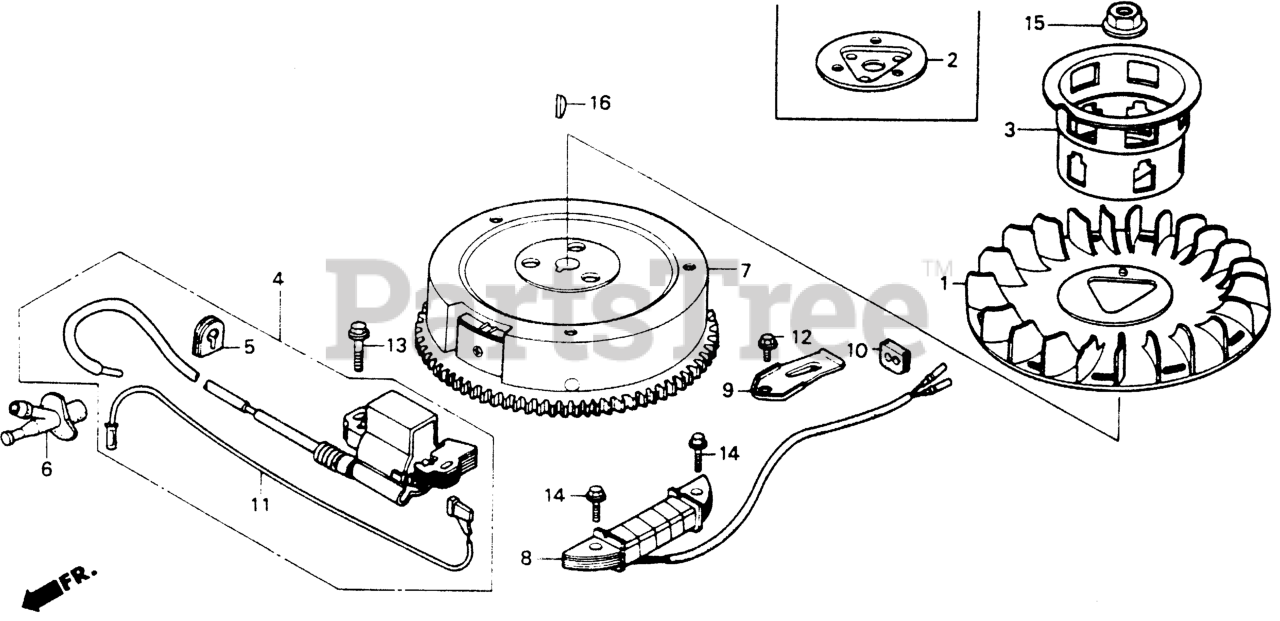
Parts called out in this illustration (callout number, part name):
1	FAN, COOLING
2	PLATE, COOLING FAN SETTING
4	COIL ASSY., IGNITION (NA USE ALT:30500-ZE9-003)
5	GROMMET, IGNITION
6	CAP ASSY., NOISE SUPPRESSOR (NOT AVAILABLE)
7	FLYWHEEL (SEL-4POLE)
8	COIL ASSY., CHARGE
9	CLAMP, WIRE
10	GROMMET, WIRE
11	WIRE, STOP SWITCH
12	BOLT, FLANGE (6X12) (CT200)
13	BOLT, FLANGE (6X28) (CT200) Use up to Engine SN 1530314.
14	BOLT, FLANGE (6X28) (CT200) Use up to Engine SN 1530314.
14	BOLT, FLANGE (6X25) Use up to Engine SN 2056819.
15	NUT, SPECIAL (16MM)
16	KEY, SPECIAL WOODRUFF (25X18)
